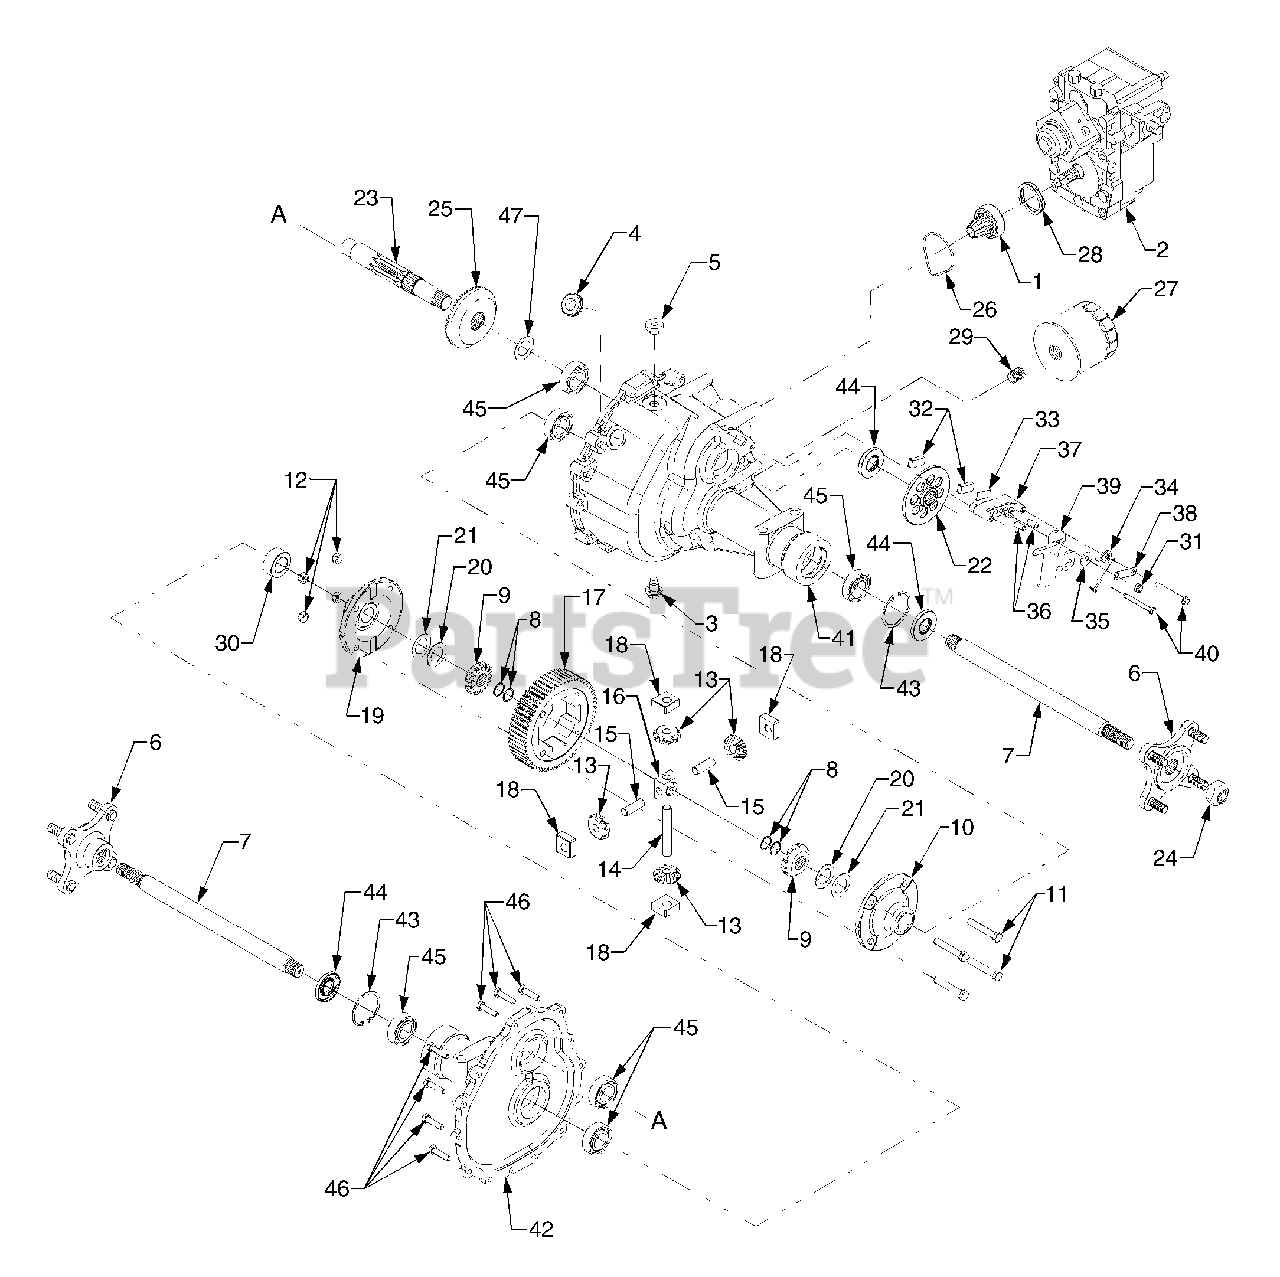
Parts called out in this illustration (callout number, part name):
1	Gear Assembly, Pinion 13T
2	Hydrostatic Transmission Assy.
3	Plug, Drain, M14 x 1.5 x .827
4	Grommet, Rubber
6	Hub Assembly, Wheel
7	Axle Shaft,
8	Retaining Ring
9	Gear, Spur, 14T
10	Housing, Diff. Cover RH
11	Hex Cap Screw, 3/8-24 x 2.25 GR5
12	Nut, Hex Lock, 3/8-24
13	Gear, Differential 10T
14	Shaft, Cross, .5 x 3.485
15	Shaft, Cross, Special
16	Differential Pinion Block
17	Gear, Spur 60T
18	Block, Thrust Miter
19	Housing, Differential Cover LH
20	Washer, Flat, 1.0 x 1.56 x .040
21	Washer, Flat, 1.0 x 1.56 x .020
22	Disc, Brake
23	Shaft, Output 9T
24	Nut, Lock, 3/4-16
25	Gear, Bevel 54T
26	Seal, Gland O-Ring
27	Filter, Oil
28	Washer, Spring
29	Fitting, Filter Nipple
30	Spacer, Axle, 1.0 x 1.665 x .71
31	Nut, Hex Insert Lock, 5/16-24
32	Pad, Brake
33	Plate, Puck
34	Spring, Torsion
35	Washer, Flat, .343 x .88 x .062
36	Pin, Brake Actuator
37	Yoke, Brake
38	Bracket, Brake Anti-Rotation
39	Arm, Brake Actuator
40	Screw, Hex Wash. Hd. Tapp 1/4-20 x 2.375
41	Housing, RH
42	Housing, LH
43	Retaining, Ring
44	Seal, Oil, 1.0 ID
45	Bearing, Ball
46	Screw, Hex Cap Locking 5/16-18 x 1.25 GR5
47	Washer, Flat, 1.0 x 1.56 x .030
